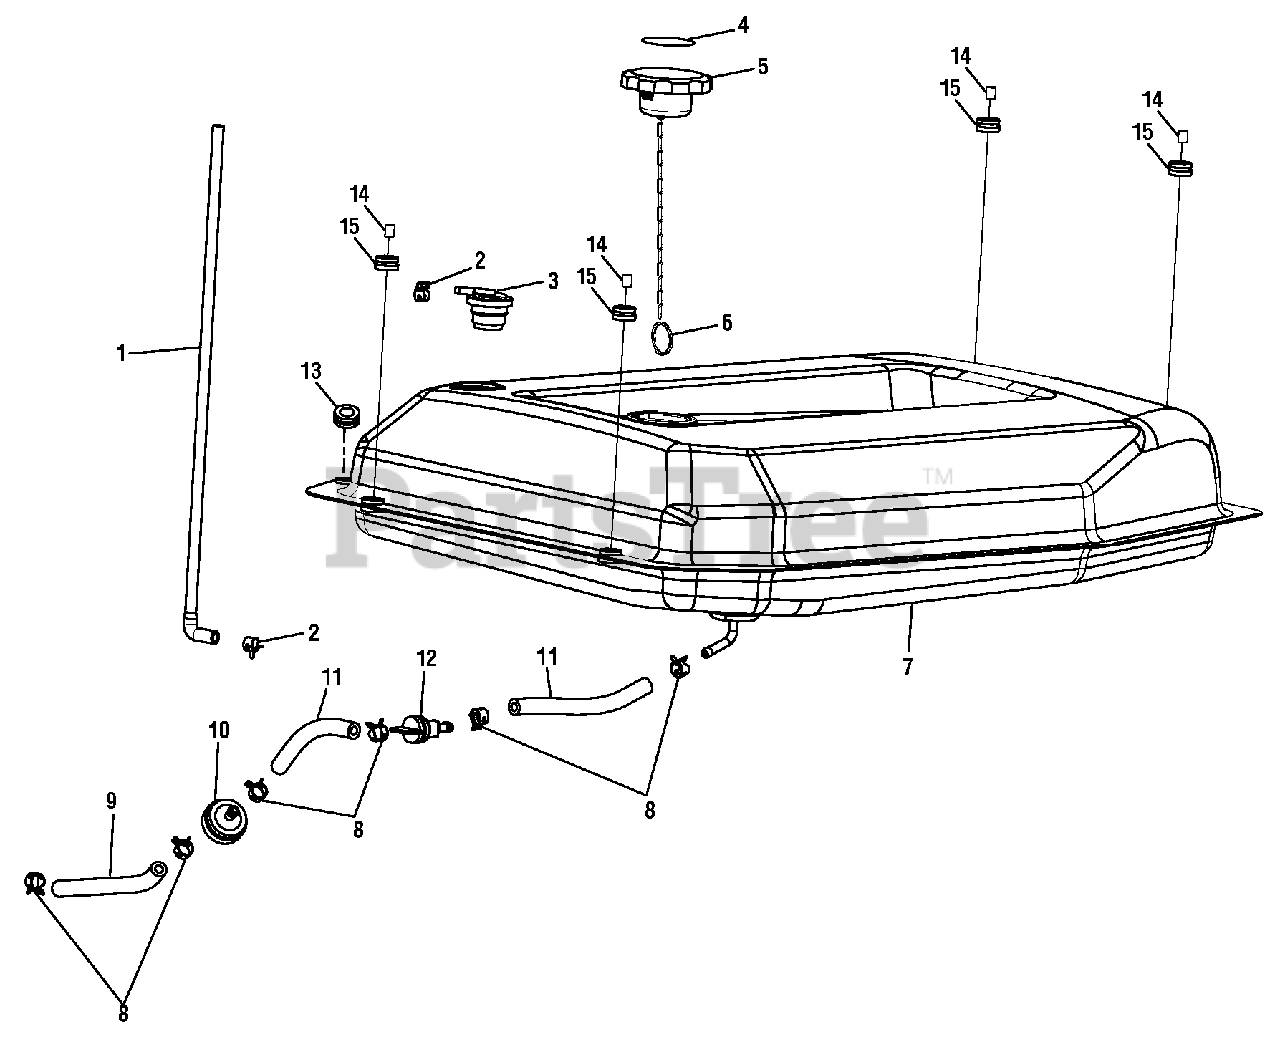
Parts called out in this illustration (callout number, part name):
1	Vapor Hose
2	Clamp (7/16 in.)
3	Fuel Tank Vapor Vent
4	Fuel Stabilizer Label
6	Ring Clip
7	Fuel Tank
8	Clamp (1/2 in.)
9	Fuel Hose
10	Fuel Filter
11	Fuel Hose
12	Fuel Shut Off Valve
